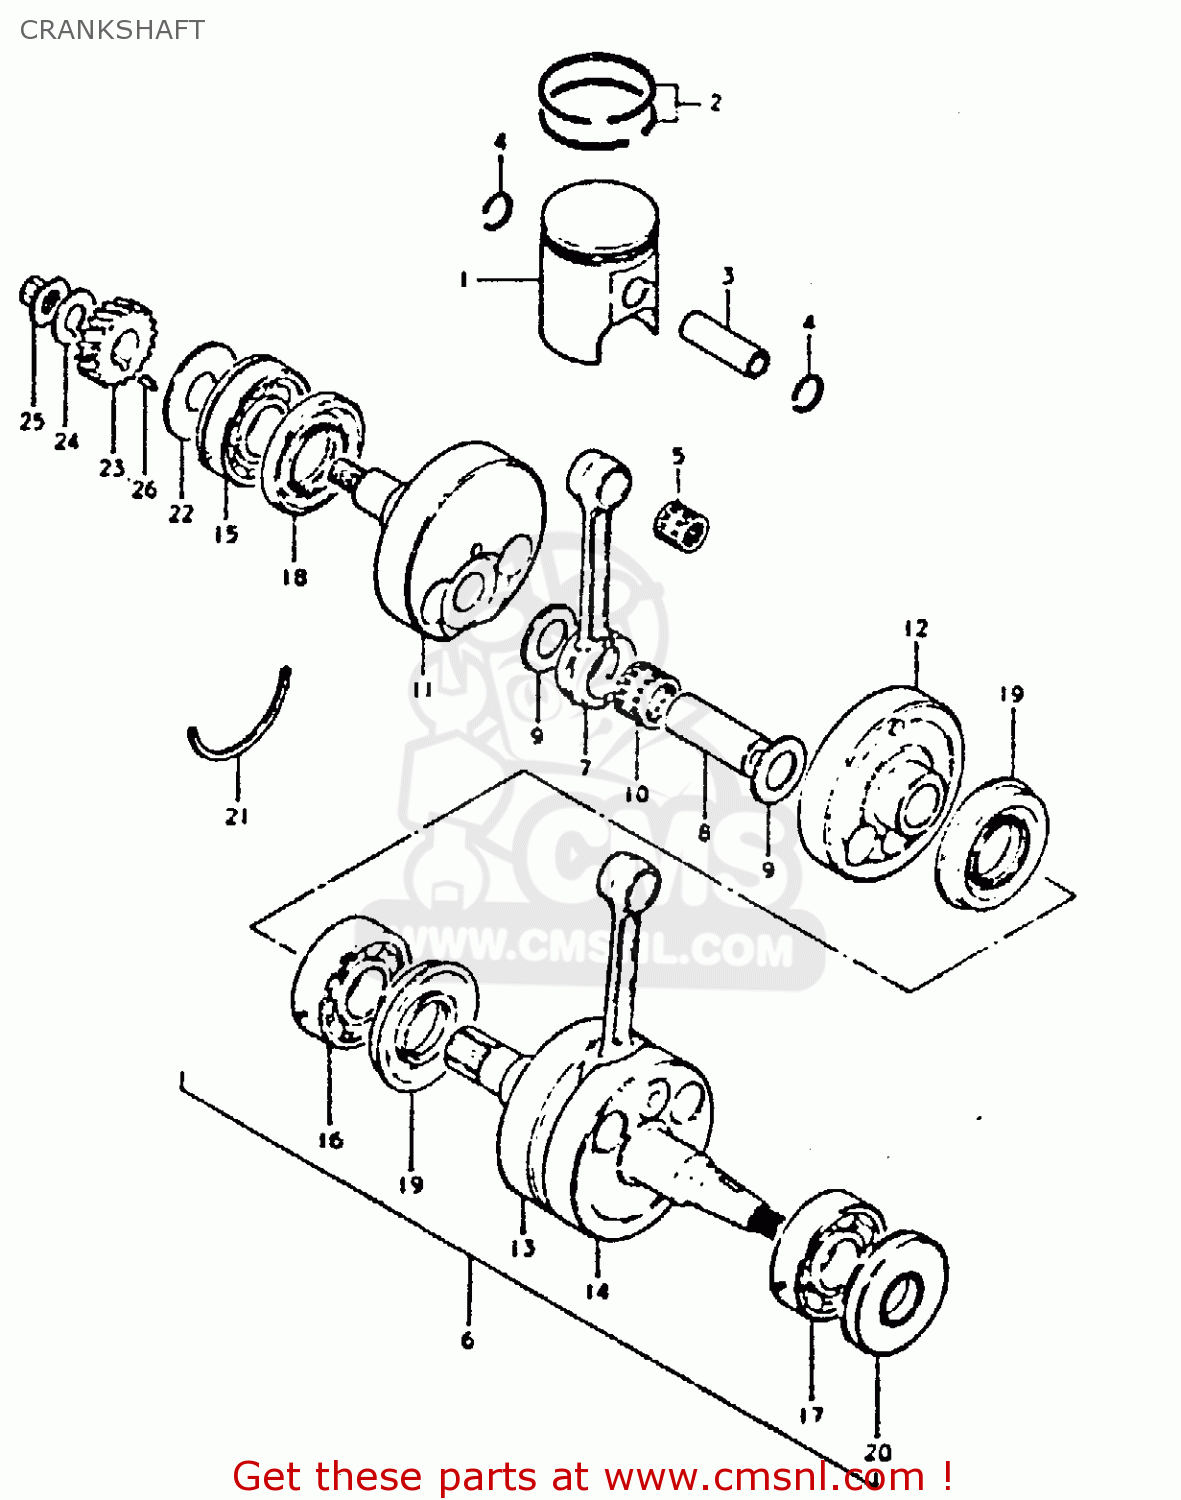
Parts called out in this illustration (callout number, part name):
1	PISTON
2	RING SET,PISTON
3	PIN,PISTON 14MM
4	RING,SNAP 14MM
5	BEARING
6	CRANKSHAFT ASSY
7	CONNECTING ROD
8	PIN,CRANK
9	WASHER(19X32X1)
10	BEARING(19X25X16)
11	CRANKSHAFT, RH
12	WEB, CRANK
13	CRANKSHAFT, MIDDLE
14	CRANKSHAFT, LH
15	BEARING(25X62X17)
16	BEARING
17	BEARING
18	OIL SEAL
19	OIL SEAL, MIDDLE
20	SEAL,OIL(25X62X8)
21	C RING
22	WASHER(20X48X1)
23	GEAR, PRIMARY DRIVE (NT:20)
24	WASHER
25	NUT
26	KEY 4MM
